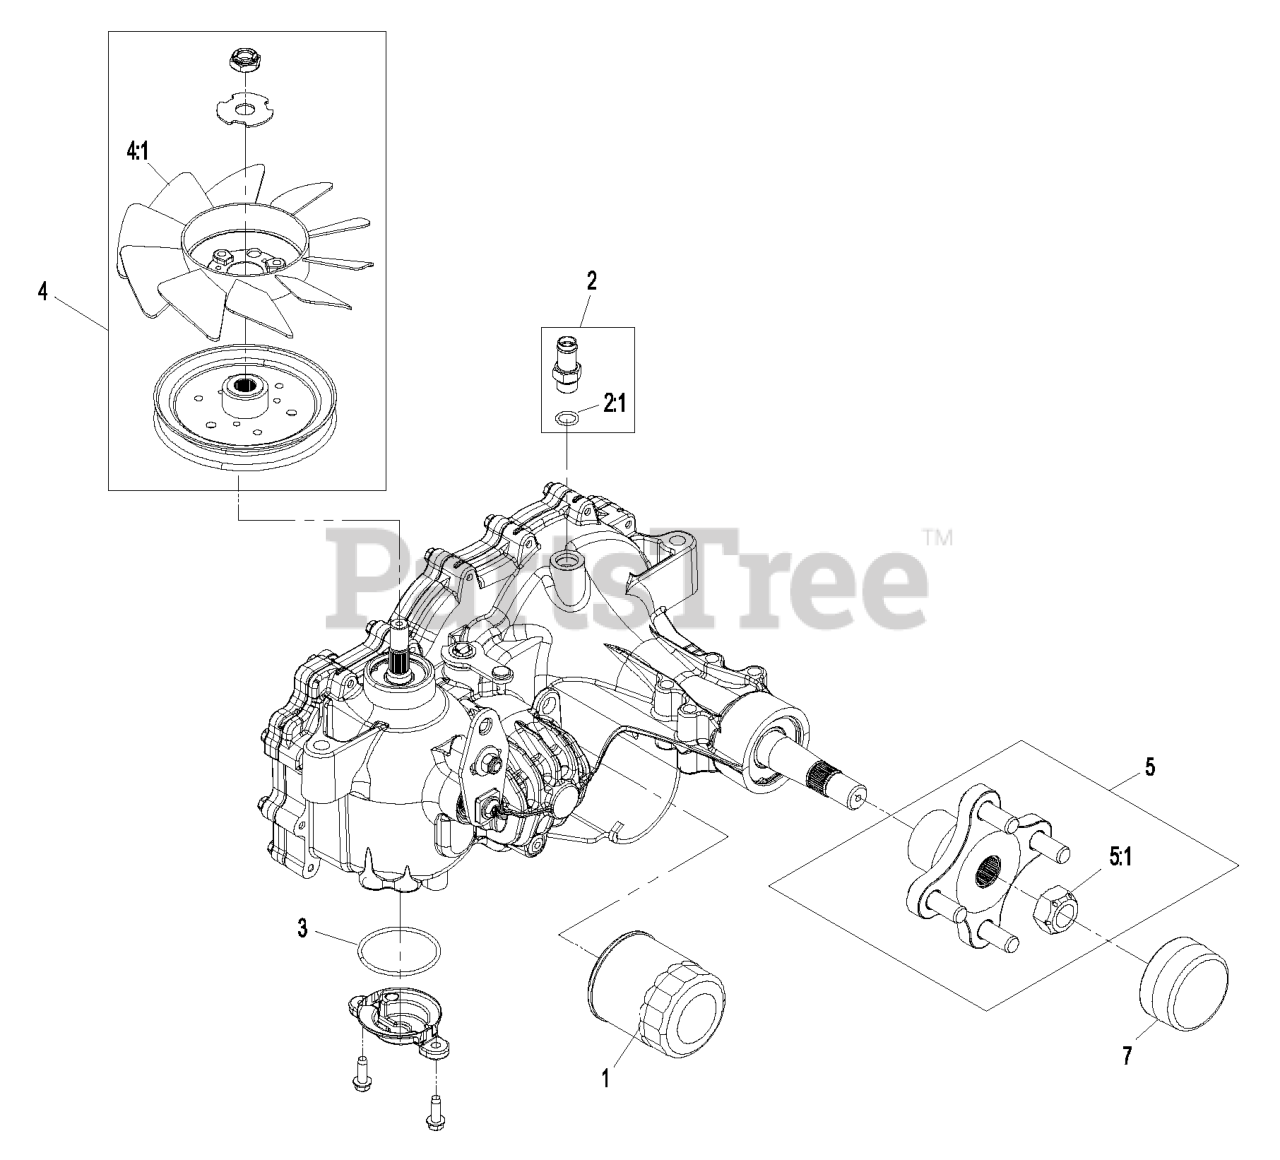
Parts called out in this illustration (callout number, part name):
1	ELEMENT-OIL FILTER, HYD
2	ADAPTER-STRAIGHT
3	O RING-SEAL
5	HUB KIT
5:1	NUT-HUB
7	COVER-NUT, AXLE
